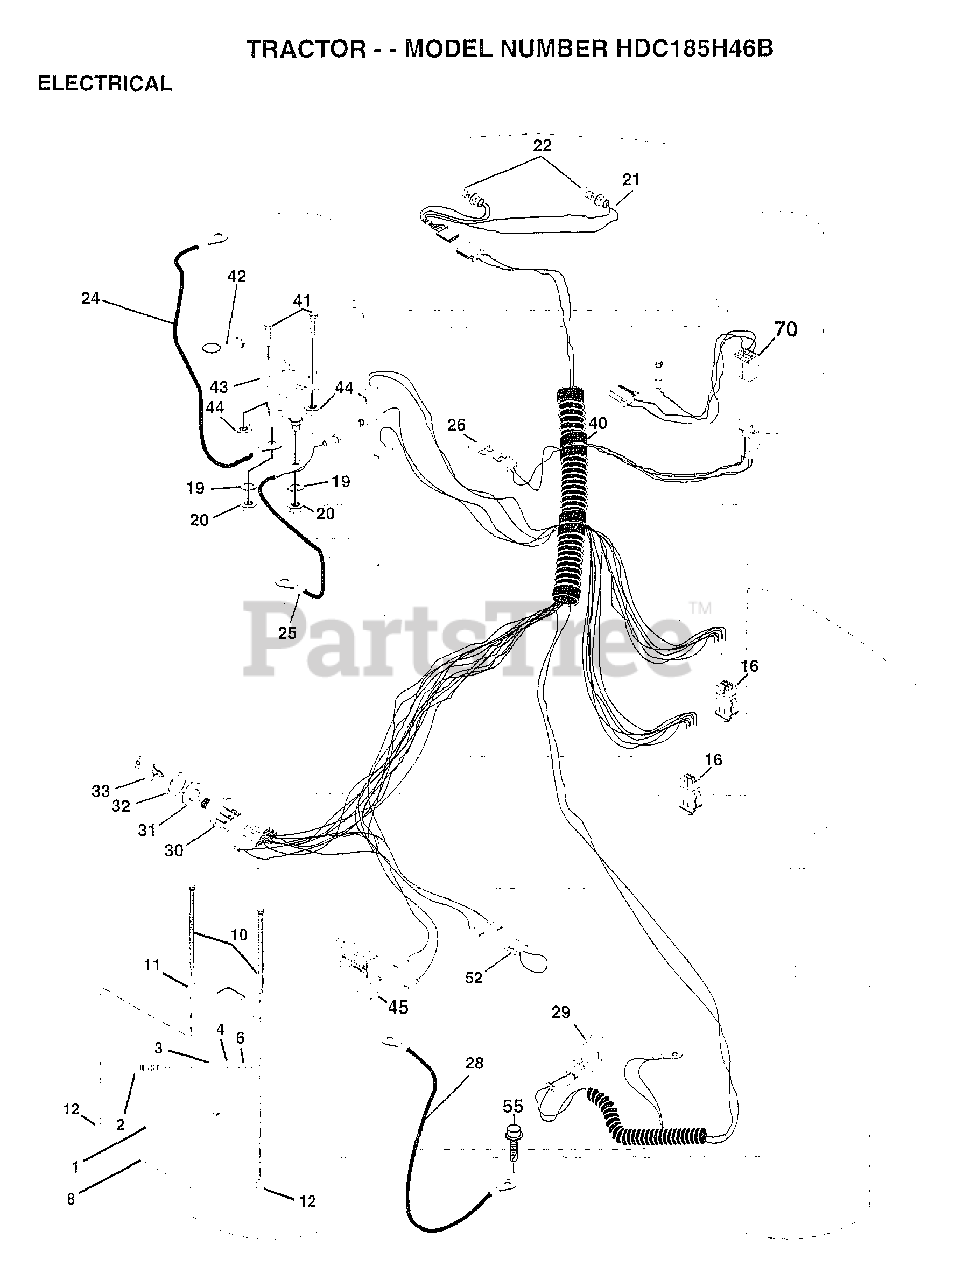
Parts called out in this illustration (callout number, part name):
2	BOLT LT
3	WASHER
4	LOCKWASHER
8	"TRAY T, BATTERY"
11	HOLDDOWN BATTERY
16	SWITCH INTERLOCK
20	NUT
21	"HARNESS,LIGHT SOC"
22	HEADLAMP BULB
24	"CABLE T, BATTERY"
25	CABLE.6GA.22W/16W
26	FUSE HYT
28	CABLE.GRND.6GA.21
29	SWITCH SEAT
30	SWITCH IGN 4POS
32	COVER KEY SWITCH
33	KEY
40	HARNESS-IGNITION
41	BOLT HXHD FIN
44	NUT HXKEP 1/4X20
52	PROTECTION LOOP
55	SCREW LT
70	HARNESS ENG DUAL
